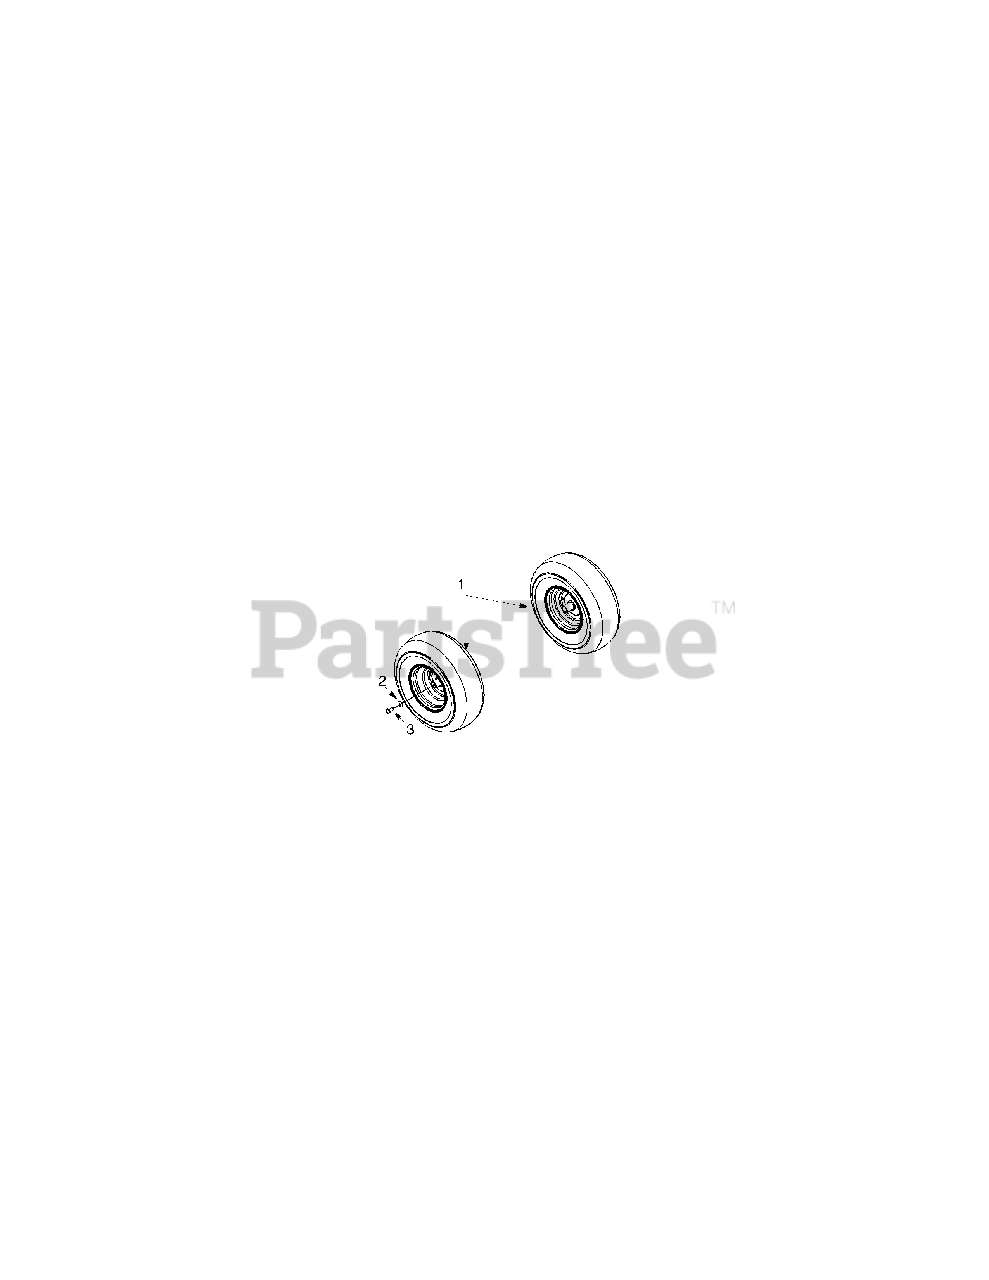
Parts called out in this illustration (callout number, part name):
1	Rear Wheel Assembly Complete: 13 x 5 x 6
2	Bell Washer .340 x .872 x .060
3	Hex Bolt 5/16-24 x .750
